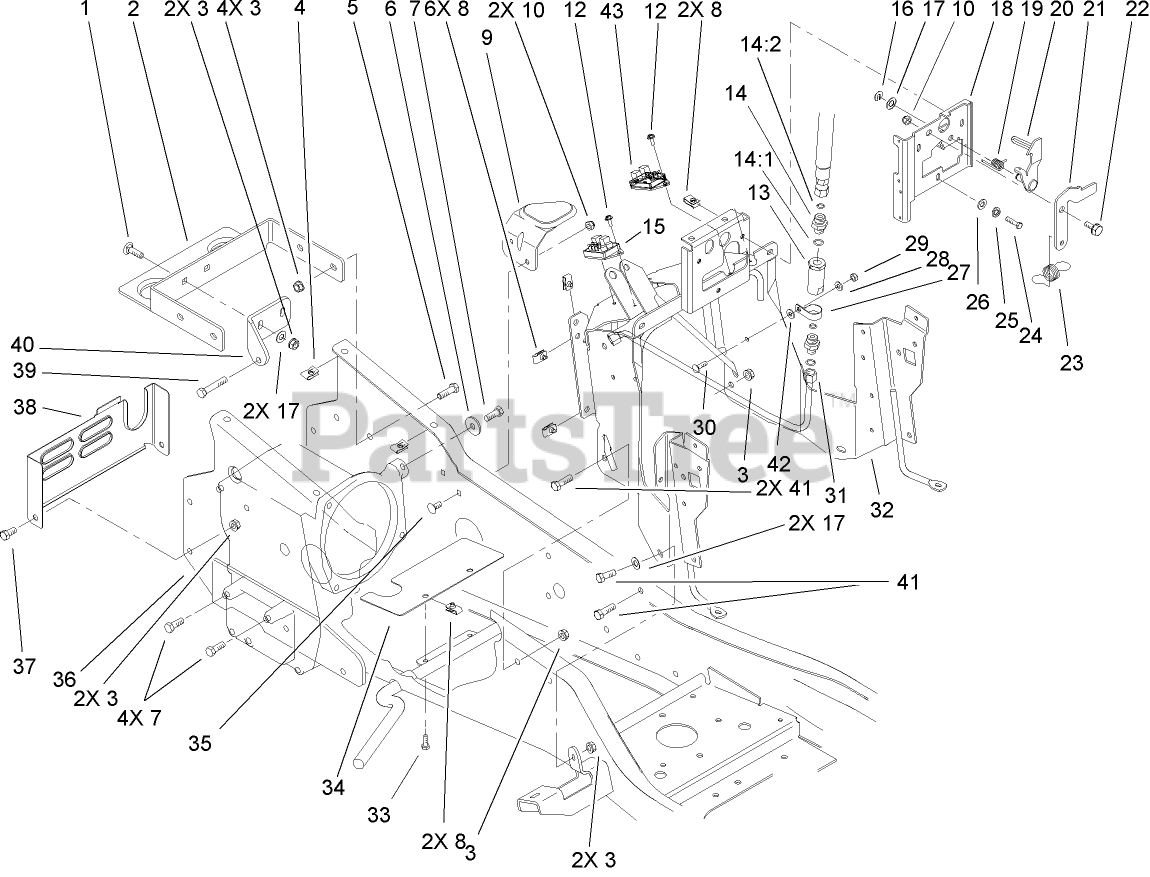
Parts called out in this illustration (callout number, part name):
1	BOLT-CARR
2	SUPPORT-GAS TANK
3	NUT-LOCK, NI
4	NUT-U
5	SCREW-HH
6	WASHER
7	SCREW-HH, LOCK
9	SUPPORT-TANK, FUEL
10	NUT-LOCK, NI
12	SCREW-HWH
13	FILTER-SCREEN, HYD
14	FITTING-STRAIGHT
14:1	O-RING
14:2	O-RING
15	MODULE-CRUISE
16	RING-RETAINING
17	WASHER-FLAT
18	BRACKET-LATCH
19	SPRING-LEVER, LATCH
21	LATCH-LEVER, TENSION
22	BOLT-SHOULDER,HFH
23	SPRING-LEVER, LATCH
24	SCREW-HH
25	WASHER-LOCK
26	WASHER-FLAT
27	CLAMP-R
28	WASHER-FLAT
29	NUT-LOCK, NI
30	BOLT-CARR
31	TUBE-HYD
32	TOWER ASM
33	SCREW-HH
34	BAFFLE-FAN
35	BOLT-CARR
37	SCREW-HH
38	COVER-REAR
39	SCREW-HH W/LOCTITE
40	STRAP-TORQUE
41	SCREW-HH
42	PUSHNUT-RETAINER, BOLT
43	MODULE-CLUTCH
